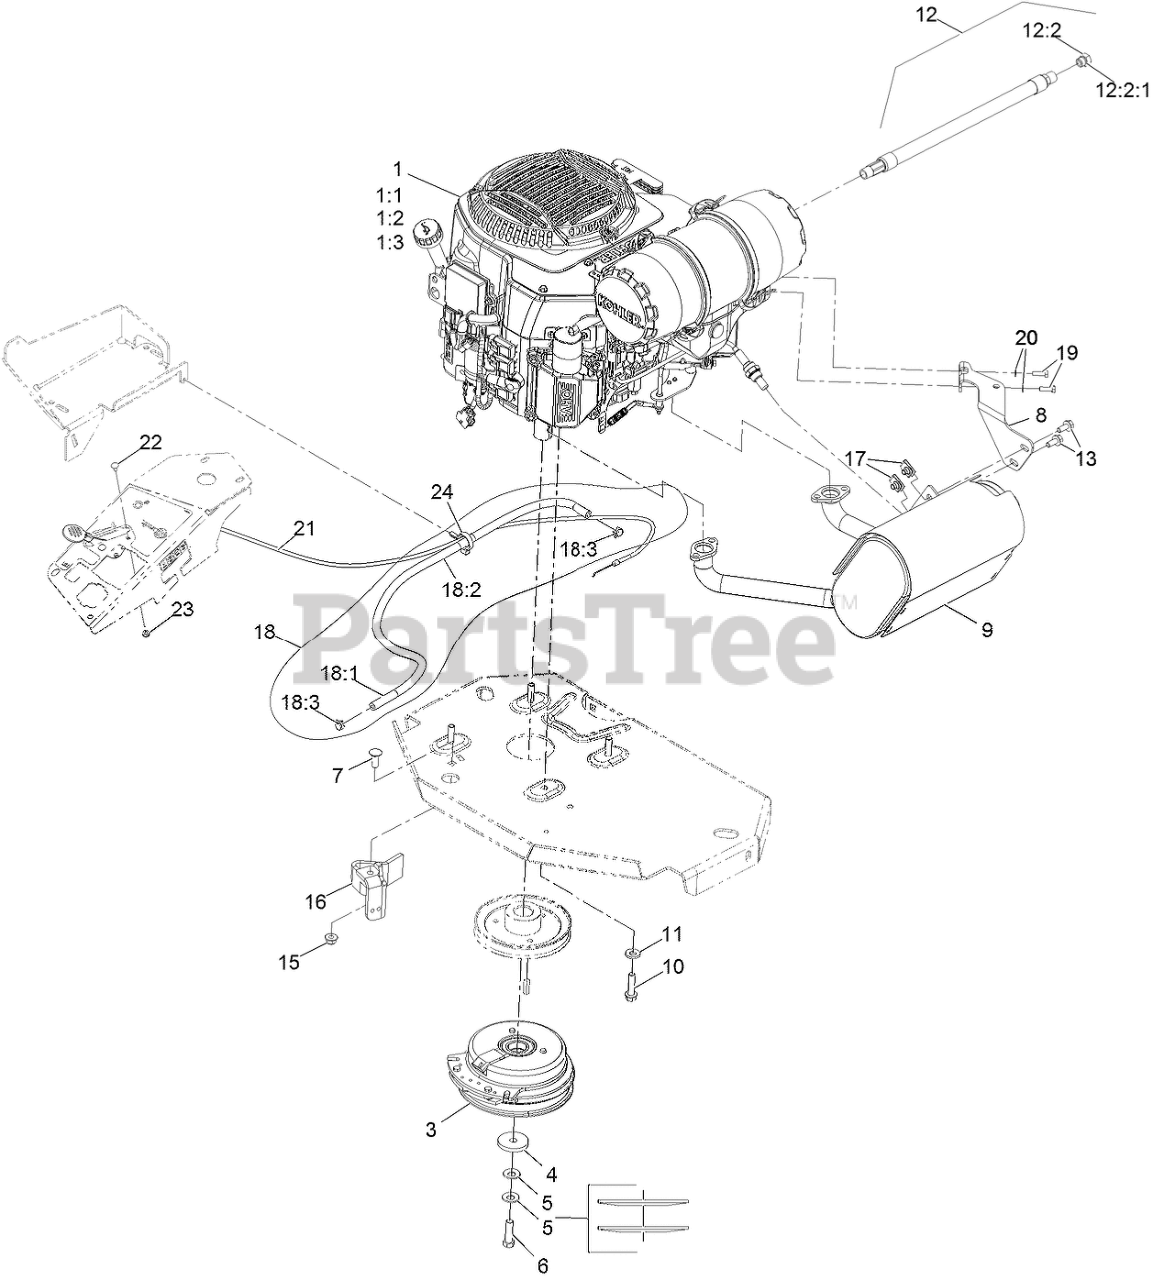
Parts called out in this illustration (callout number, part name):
1:1	Kohler 52 050 02-S Engine Oil Filter
1:2	Kohler 25 083 01-S Engine Air Filter
1:3	Kohler 25 083 04-S Safety Filter
3	CLUTCH KIT
4	WASHER-CLUTCH
5	WASHER-SPRING
6	SCREW-HH 7/16-20 X 1 1/2 W/LOCTITE
7	SCREW-CARR
8	MUFFLER BRACKET KIT
9	MUFFLER KIT
10	SCREW-HWH
11	WASHER-BELLEVILLE
12	OIL DRAIN HOSE ASM
12:2	PLUG-HH
12:2:1	O-RING
13	SCREW-HHF
15	NUT-HF, NI
16	CLUTCH-ANCHOR
18	FUEL LINE ASM
18:1	HOSE-FUEL
18:2	SLEEVE-THERMAL
18:3	CLAMP-HOSE
19	SCREW-HH M6-1 X 20Mm W/Patch
20	WASHER-SPRING
21	ASM,THROTTLE CABLE
22	BOLT-CARR
23	NUT-LOCK, NI
24	CLAMP-HOSE
